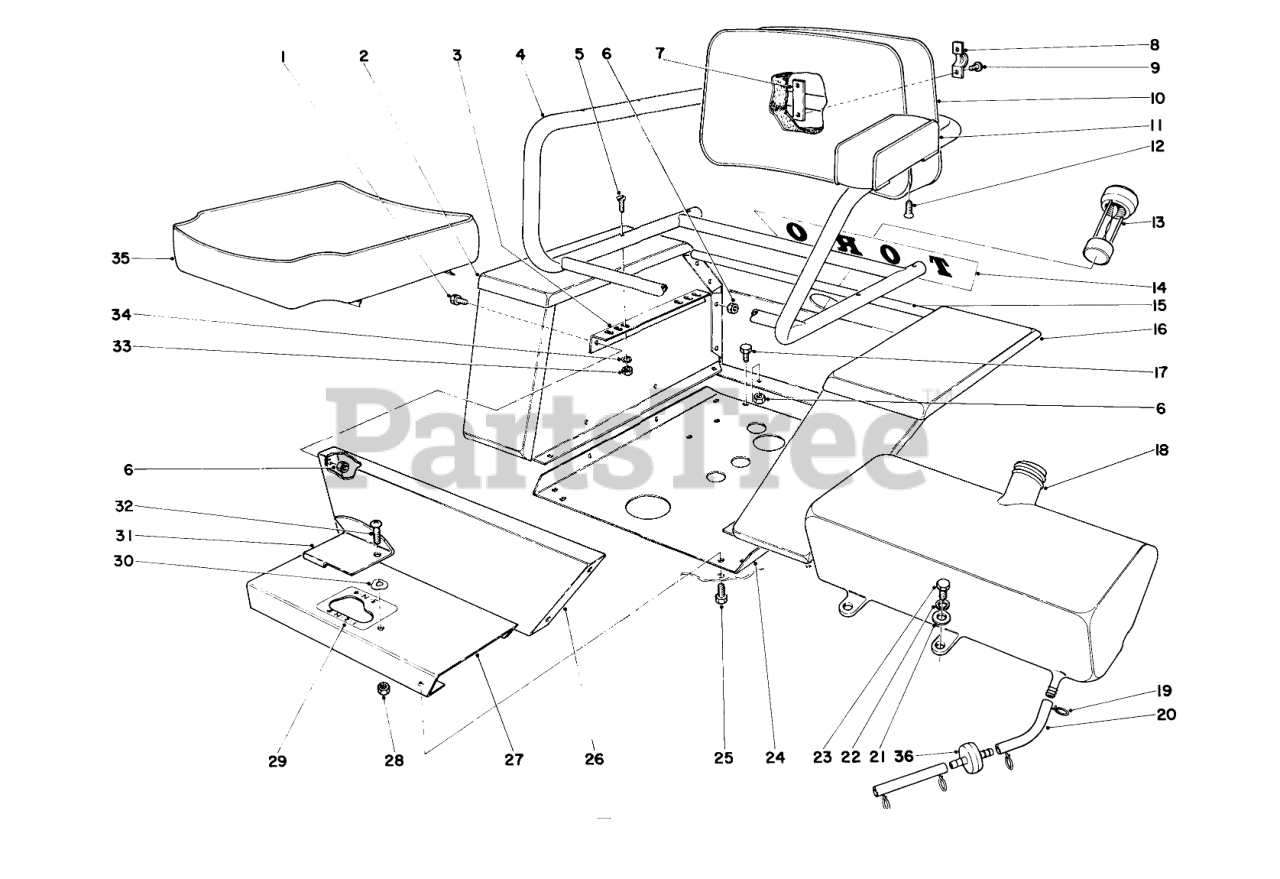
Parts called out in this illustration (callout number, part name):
1	SCREW-HH
2	Fender R.H.
3	Brace Fender
4	Frame Seat
5	Flat Head Screw
6	NUT-LOCK, CONE
7	Plate Clamp
8	U-Clamp
10	Backrest Seat
11	Arm Rest Seat
12	Flat Head Screw
13	Gas Gauge
14	Decal Seat
15	Rear Fender
16	Fender L.H.
17	SCREW-HH
18	Gas Tank
19	Clamp
20	Gas Hose
21	WASHER-FLAT
22	WASHER-LOCK
23	SCREW-HH
24	Base Fender Rear
26	Fender Front
27	Shift Pattern
28	NUT-LOCK, CONE
29	Decal Shift Pattern
30	Lynch Pin
31	Tab Lock out
33	NUT-HEX
34	WASHER-LOCK
35	Cushion Seat
36	Filter Gas Tank
